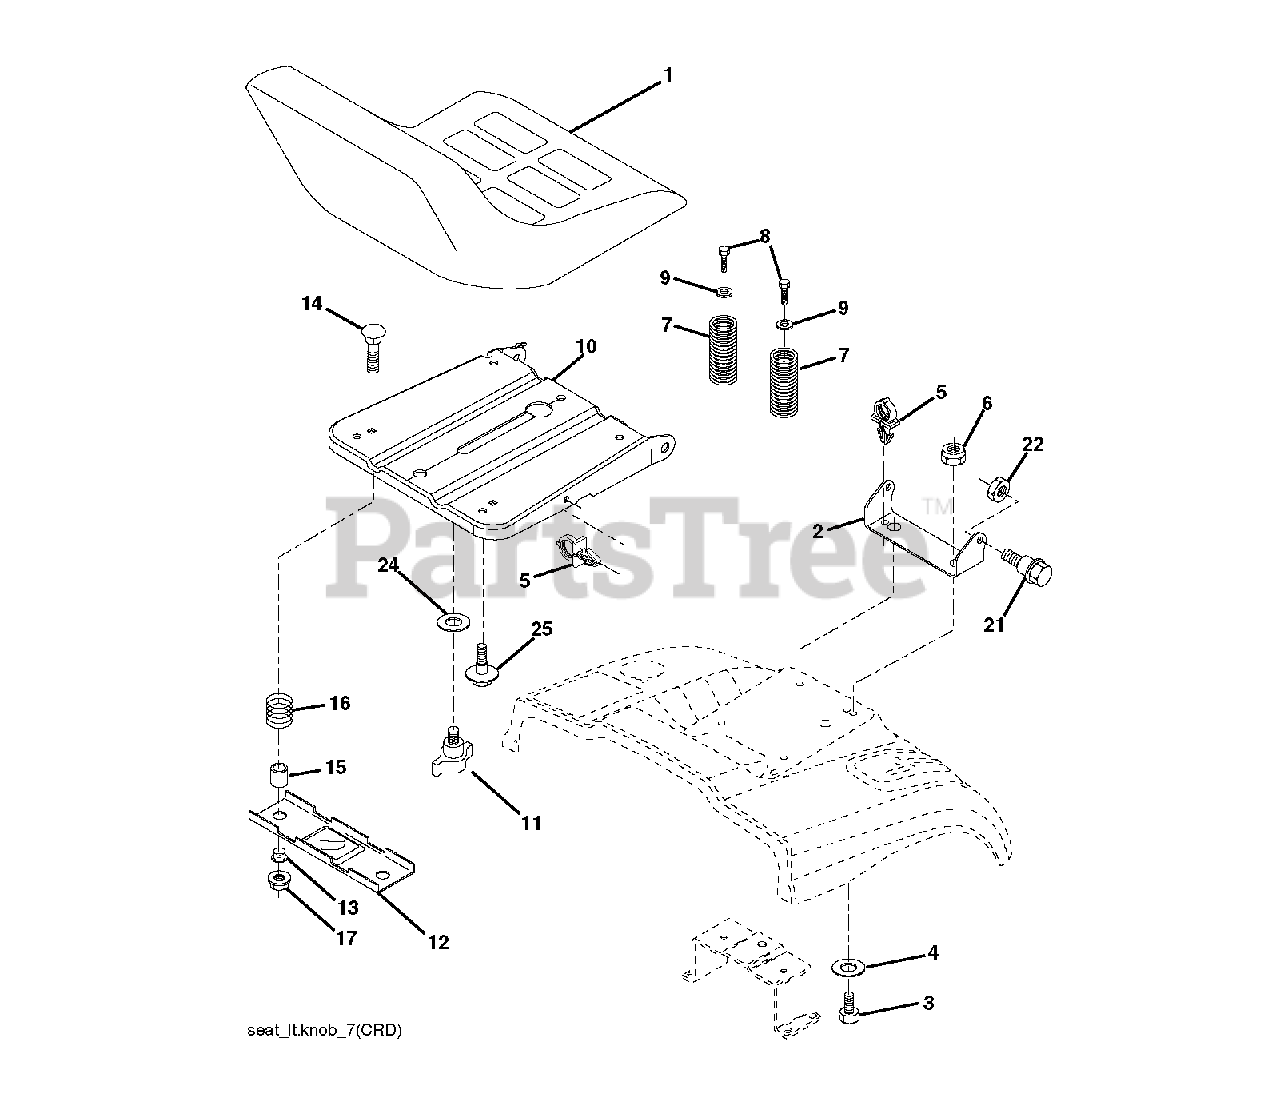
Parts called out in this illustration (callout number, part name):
1	SEAT.XG150.BLK.KB/SLD.NO-LOGO
2	SEAT PIVOT BRKT
4	WASHER PM
5	PUSH CLIP
6	NUT
7	SPRING COMPRESSION
8	SCREW 3/8-16X1
9	WASHER
10	PAN.ASM.SEAT.1SLOT
11	KNOB.SEAT.ADJ.WINGNUT
12	BRKT.MNTNG.SWITCH.SEAT
14	BOLT.ROUND.HEAD.SQUARE.NECK
15	SPACER SPLIT
16	SPRING COMPRESSED
17	NUT T
21	BOLT.SHOULDER.5/16-18
22	NUT.71038.31-18.HEX.NYLOCK
25	BOLT,SHOULD
